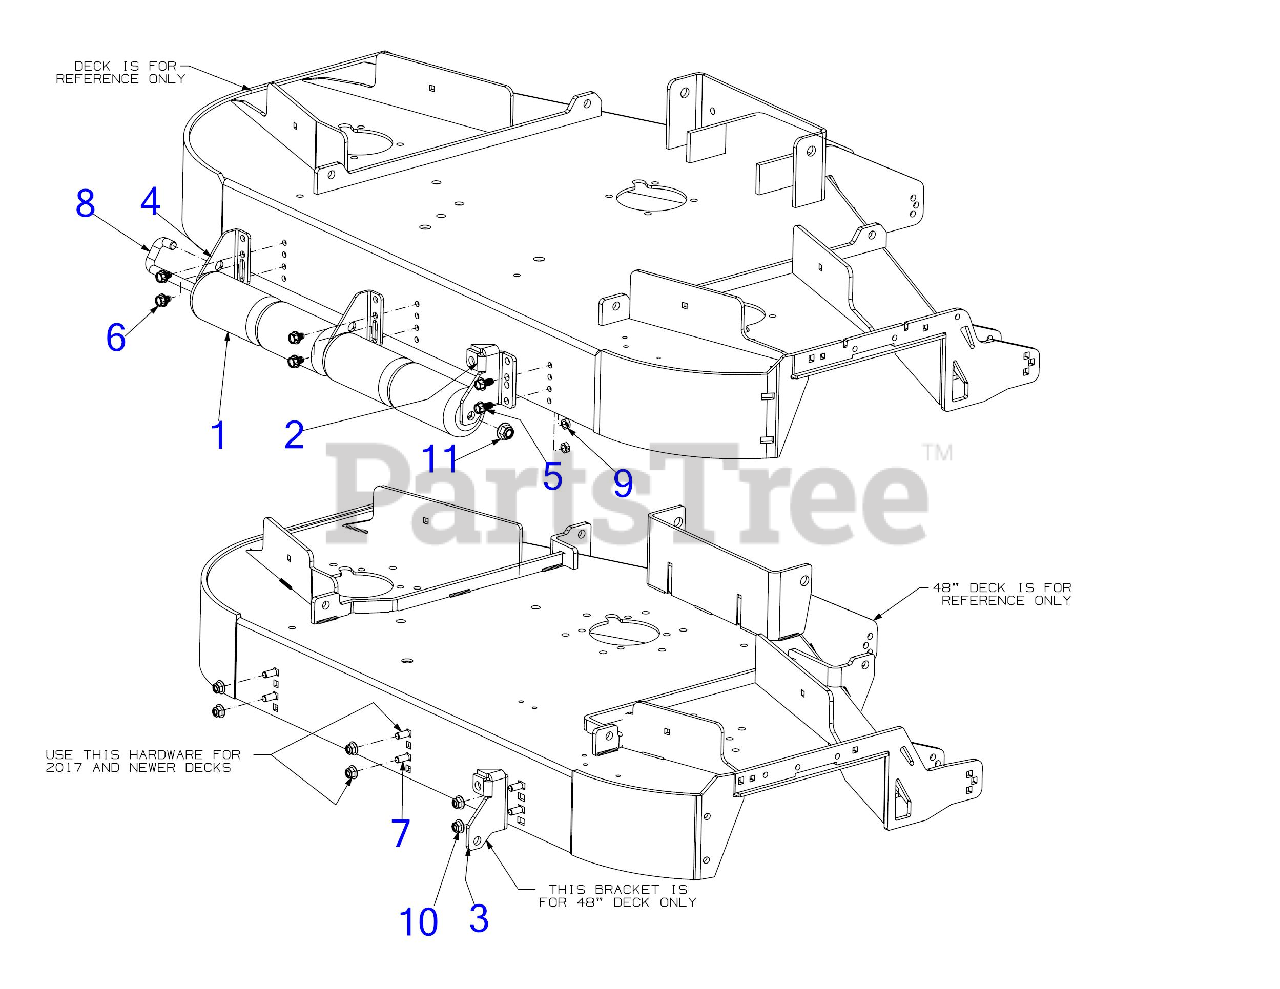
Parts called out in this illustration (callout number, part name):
1	ROLLER ASSEMBLY
5	SCREW 3/8-16 x 3/4
6	SCREW 3/8-16 x .500
7	CARRIAGE BOLT 3/8-16 x 1.00 GR5
8	ROLLER PIN
9	JAM LOCK NUT
